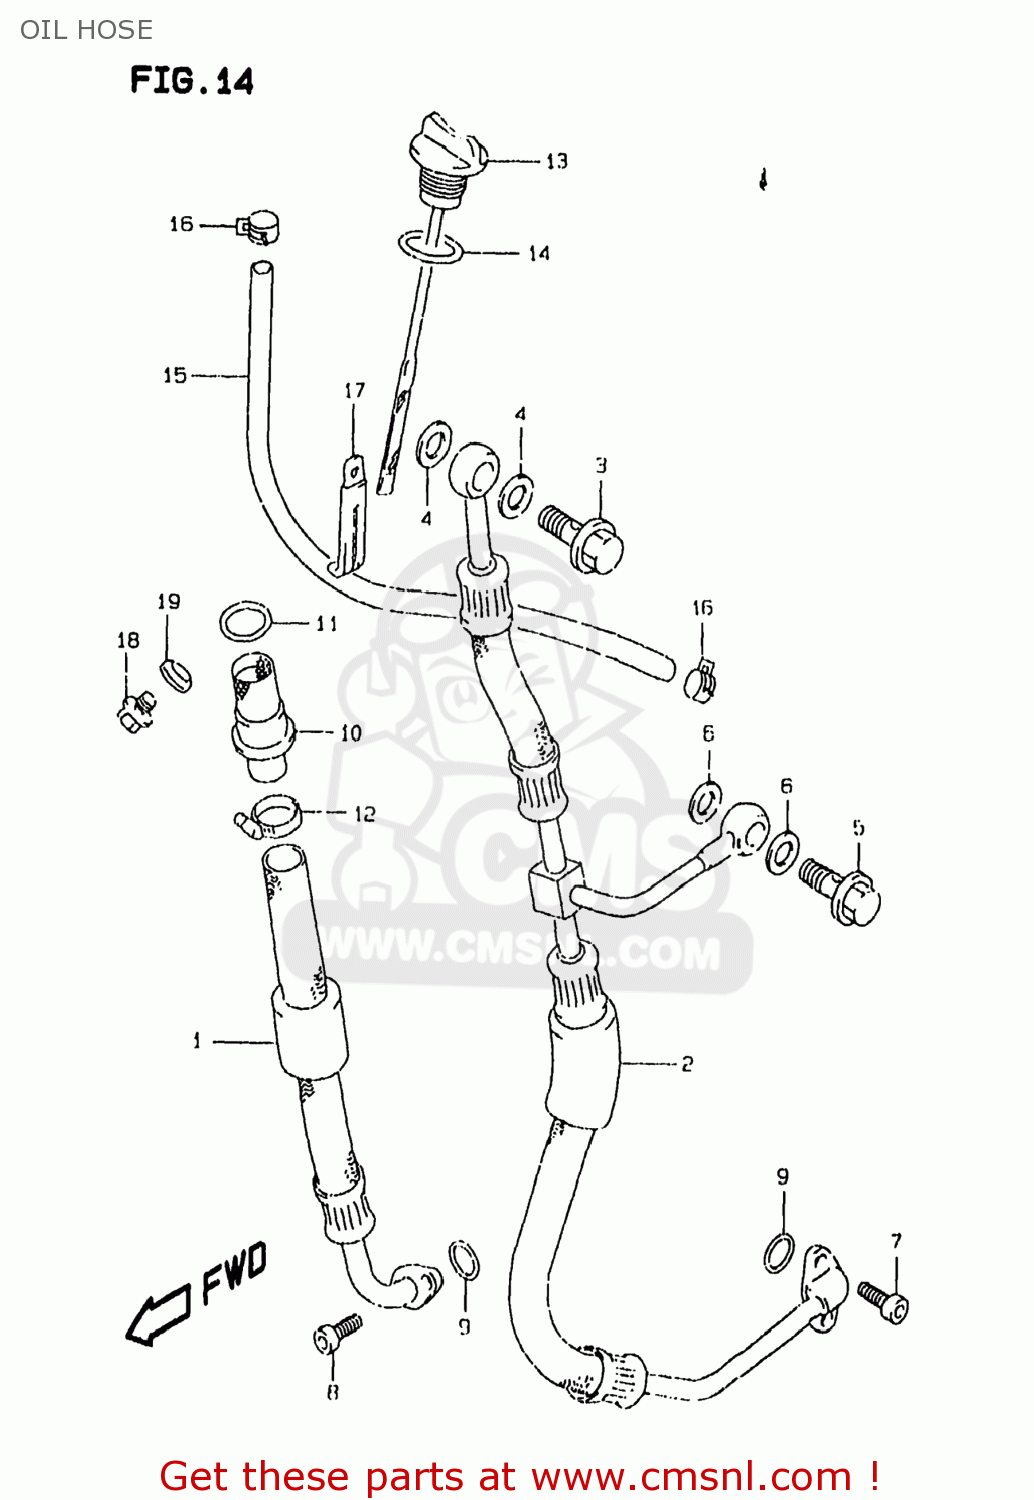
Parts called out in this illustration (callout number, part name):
1	HOSE,OIL TANK INLET
2	HOSE,OIL TANK
3	BOLT UNION
4	GASKET(16X22X2) (NAS)
5	BOLT UNION
6	GASKET(12X17X1) (NAS)
7	BOLT,OIL FILLE
8	BOLT,CRKCASE,R
9	O RING(D:2.4,ID:12.3)
10	STRAINER,FRAME HEAD UNDER
11	O RING(D:3.1,ID:22.7)
12	CLAMP
13	GAUGE ASSY,OIL LEVEL
14	O RING(D:3.1,ID:16.8)
15	HOSE,OIL OVER FLOW
16	CLIP
17	CLAMP(L:55)
18	PLUG(10X12)
19	GASKET(10X14X3.6) (NAS)
